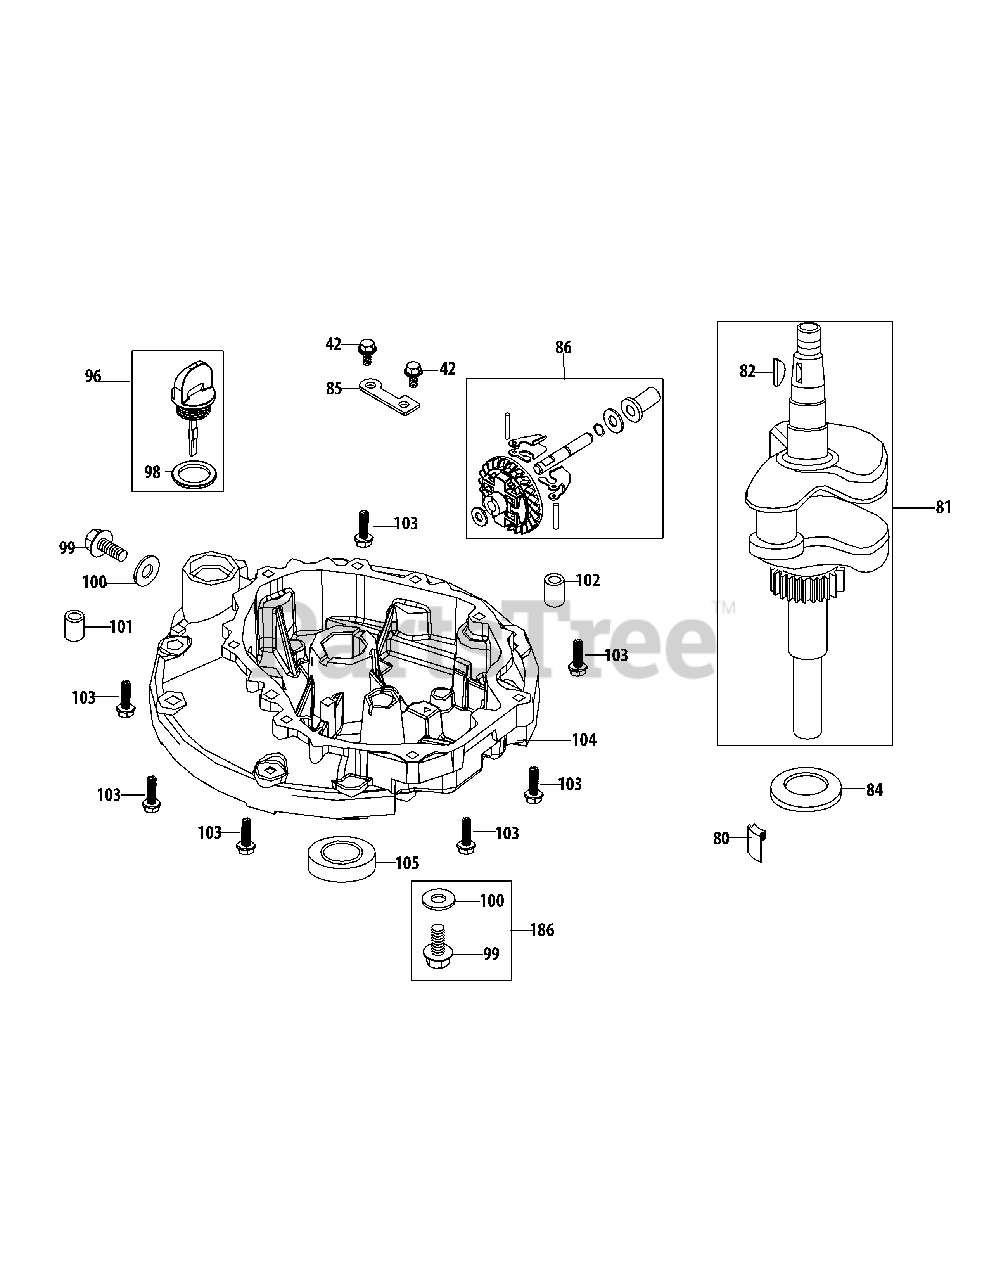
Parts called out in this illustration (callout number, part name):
80	Oil Return Seal
81	Crankshaft Assembly
82	Flywheel Key
84	Crankshaft Thrust Washer
85	Governor Gear Mounting Plate
86	Governor Gear/Shaft Assembly
96	Dipstick Assembly
98	Dipstick O-Ring
99	Oil Drain Plug
100	Oil Drain Plug Washer
101	Crankcase Cover Dowel Pin 9×14
102	Crankcase Cover Dowel Pin 7×14
103	Bolt M6X28
104	Crankcase Cover
105	Lower Crankshaft Seal
186	Oil Drain Plug And Washer Ass'y
